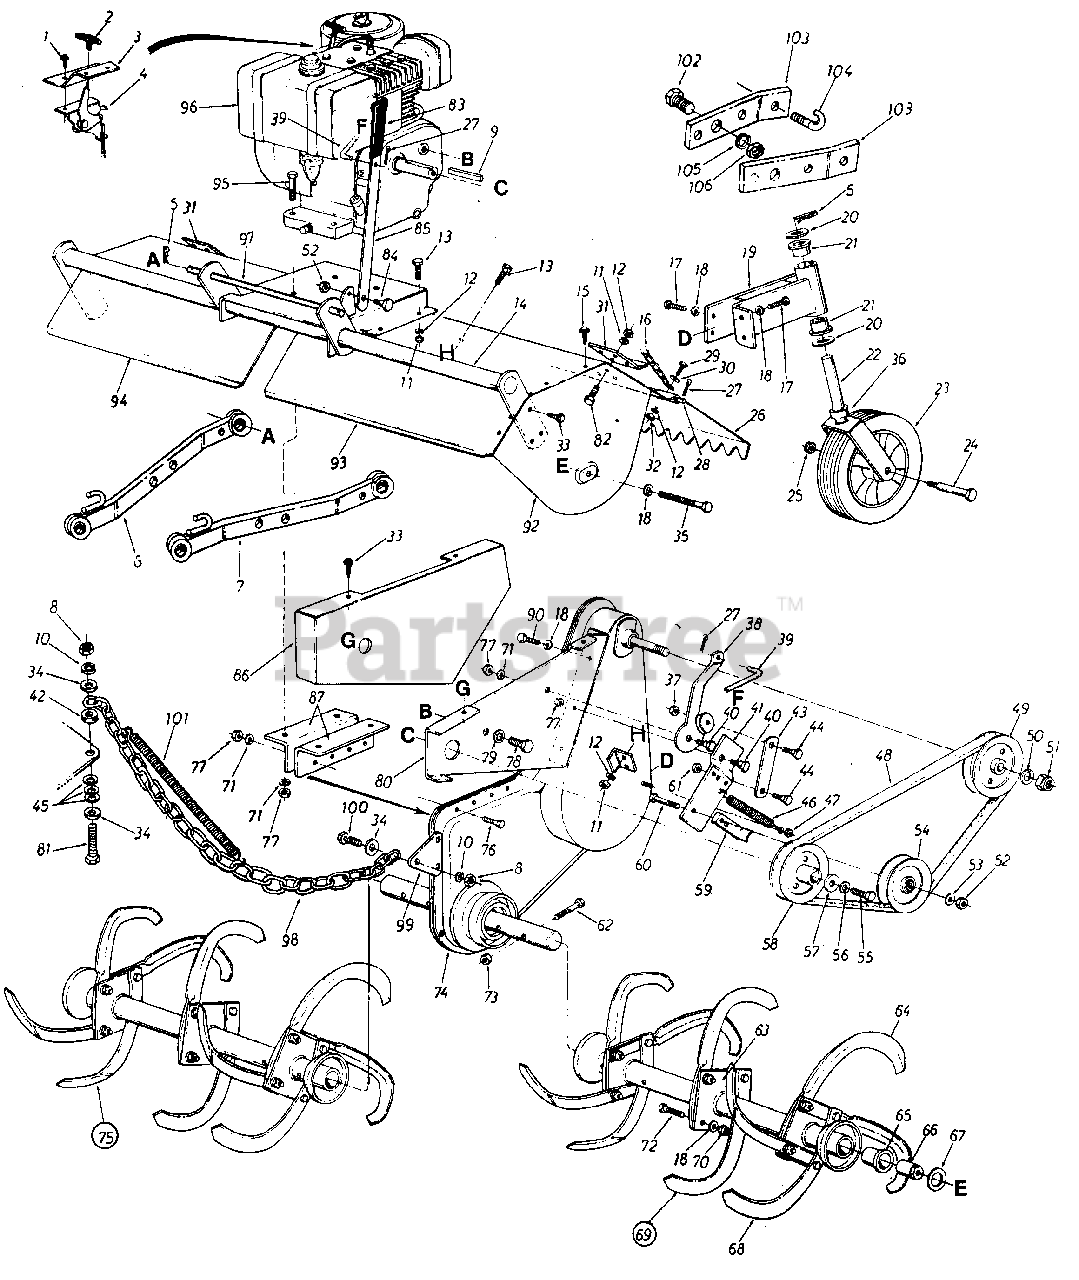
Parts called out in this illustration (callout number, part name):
1	Hex Wash. Hd. Self-Tap Scr. #8 x .50" Lg .
2	Throttle Control Knob
3	Throttle Control Bracket
4	Throttle Control Ass'y. Comp.
5	Internal Cotter Pin
6	Draft Bar Ass'y.-R.H.
7	Draft Bar Ass'y.-L.H.
8	Hex Nut 3/8-24 Thd.
9	Sq. Key 1/4" X 1/4" X 2.00" Lg.
10	L-Wash. 3/8" I.D.
11	Hex Nut 1/4-28 Thd.
12	L-Wash. 1/4" I.D.
13	Hex Bolt 1/4-28 x .62" Lg.*
16	#2 Dog Chain x 20" Lg.
17	Hex Wash. Hd. Self-Tap Scr. 318-24 x .75" Lg.
18	L-Wash. 3/8" I.D.
19	Swivel Wheel Support
20	Fl-Wash. 3/4" I.D. x 1.50" O.D.
21	Flange Bearing 3/4" I.D. x 1.00" O.D.
22	Swivel Wheel Caster
23	Wheel Assembly 10.0 x 2.75
24	Shoulder Bolt .623" I.D. x 3.62" Lg.
25	Hex Cent. L-Nut 7/16-14 Thd.
28	L.H. Flap Rod
28	R.H. Flap Rod
29	Hex Bolt 1/4-20 x .62" Lg.
30	Fl-Wash. 1/4" I.D.
33	Hex Wash. Hd. Self-Tap Scr. 1/4" x .62" Lg.
34	Fl-Wash. .385" I.D. x 1.0" O.D. x .135 Thk.
35	Hex Bolt 3/8-16 x 1.25" Lg.
36	Spacer .752" I.D. x 1.25" O.D.
37	Hex Cent. L-Nut 5/16-18 Thd.
40	Shoulder Bolt 7/16" Dia. x 1.75" Lg.
45	Fl-Wash. .406" I.D. x .74" O.D. x .063 Thk.
46	Extension Spring .62" O.D. x 6.12" Lg.
47	Hex Crown Nut 3/8-24 Thd.
48	V-Belt 1/2" X 43" Lg. (Kevlar)
49	1/2" "V"-Pulley 4.75" O.D. x .625" Bore
50	L-Wash. 5/8" I.D.
51	Hex Ins. L-Nut 5/8-18 Thd.
52	Hex Cent. L-Nut 3/8-16 Thd.
53	Fl-Wash. 3/8" I.D.
54	Idler Pulley 4.0" O.D.
55	Hex Bolt
56	L-Wash. 7/16" I.D.
57	Fl-Wash. 7/16" I.D. x 1.38" O.D.
58	1/2" "V"-Pulley .475" O.D. x 1.00" Bore
61	Hex Cent. L-Nut 5/16-18 Thd.
62	Hex Bolt 7/16-14 x 2.00" Lg.
65	Flange Bearing 1.00" I.D.
66	Spacer
67	Thrust Wash. 1/2" I.D. x 1.55" O.D.
68	Tine-R.H.
69	Tine Assembly Comp.-L.H.
70	Hex Nut 3/8-24 Thd.
71	L-Wash. 5/16 I.D.*
72	Hex Bolt 3/8-24 x 1.5" Lg.
73	Hex Cent. L-Nut 7/16-14 Thd.
77	Hex Nut 5/16-18 Thd.
78	Hex Bolt 1/2-20 x .88" Lg. (Grade 5)
79	L-Wash. 1/2" I.D.
80	Clutch Support Bracket
81	Hex Bolt 3/8-24 x 1.75" Lg.
82	Hex Bolt 1/4-28 x .75" Lg.
83	Plastic Grip
84	Shoulder Bolt .498 Dia. x .212 Lg.
85	Clutch Handle
86	Clutch Support Shroud
87	Engine Mounting Bracket
90	Hex Bolt 3/8-16 x .62" Lg.
92	L.H.-Side Plate
96	8 H.P. Engine
97	Tiller Mounting Shaft 16" Lg
98	Chain 23" Lg.
99	Tiller Mounting Bracket
100	Hex Bolt 3/8-24 x 1.25" Lg.*
101	Extension Spring
102	Hex Bolt 5/8-18 x 1.62 Special
103	Drag Link Extension
104	Hitch Chain Hook
105	L-Wash. 5/8" I.D.*
106	Hex Jam Nut 5/8-18 Thd.
